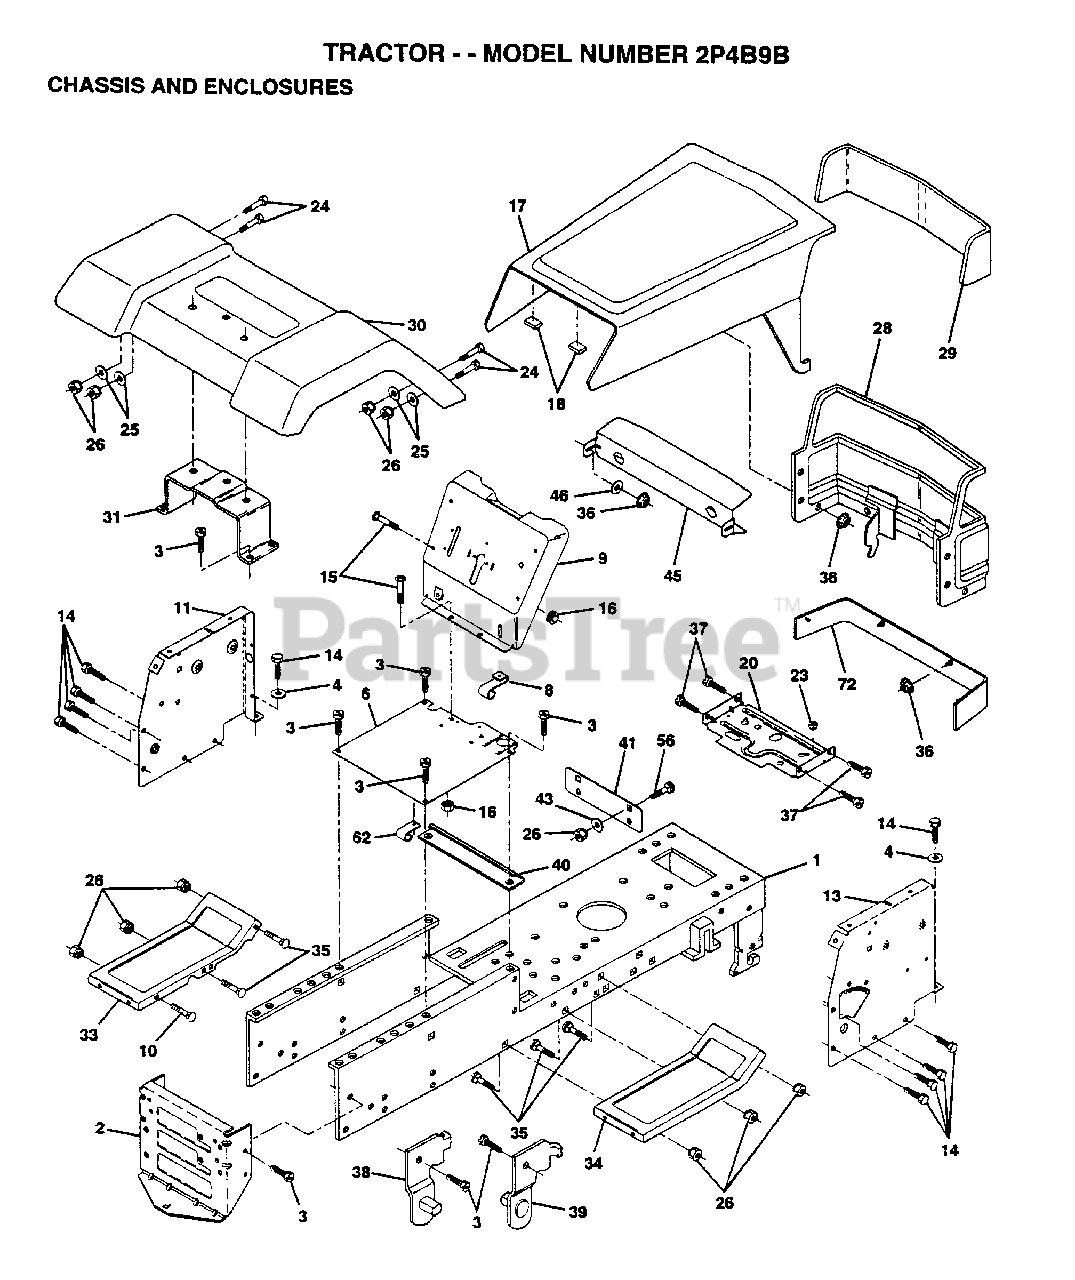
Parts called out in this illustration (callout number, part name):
1	CHASSIS.WLD.11GA
3	SCREW
4	WASHER
8	"CLIP,INSULATOR"
11	DASH PANEL LH
14	SCREW LT
15	SCREW
24	BOLT
25	WASHER
26	NUT
28	GRILLE.WLD.RLY.LT
31	BRACKET SUPT FEND
33	FOOTREST.LH.LT/GT
34	FOOTREST.RH.LT/GT
35	BOLT
36	PAL NUT LT
37	SCREW
38	BRACKET ASM LH
39	BRACKET ASM RH
40	SPACER FENDER LT
41	PLATE EXTEN FEND
43	WASHER
46	RETAINER
56	BOLT
60	LOCKWASHER.5/16.E
72	STRAP ASM GRILL
